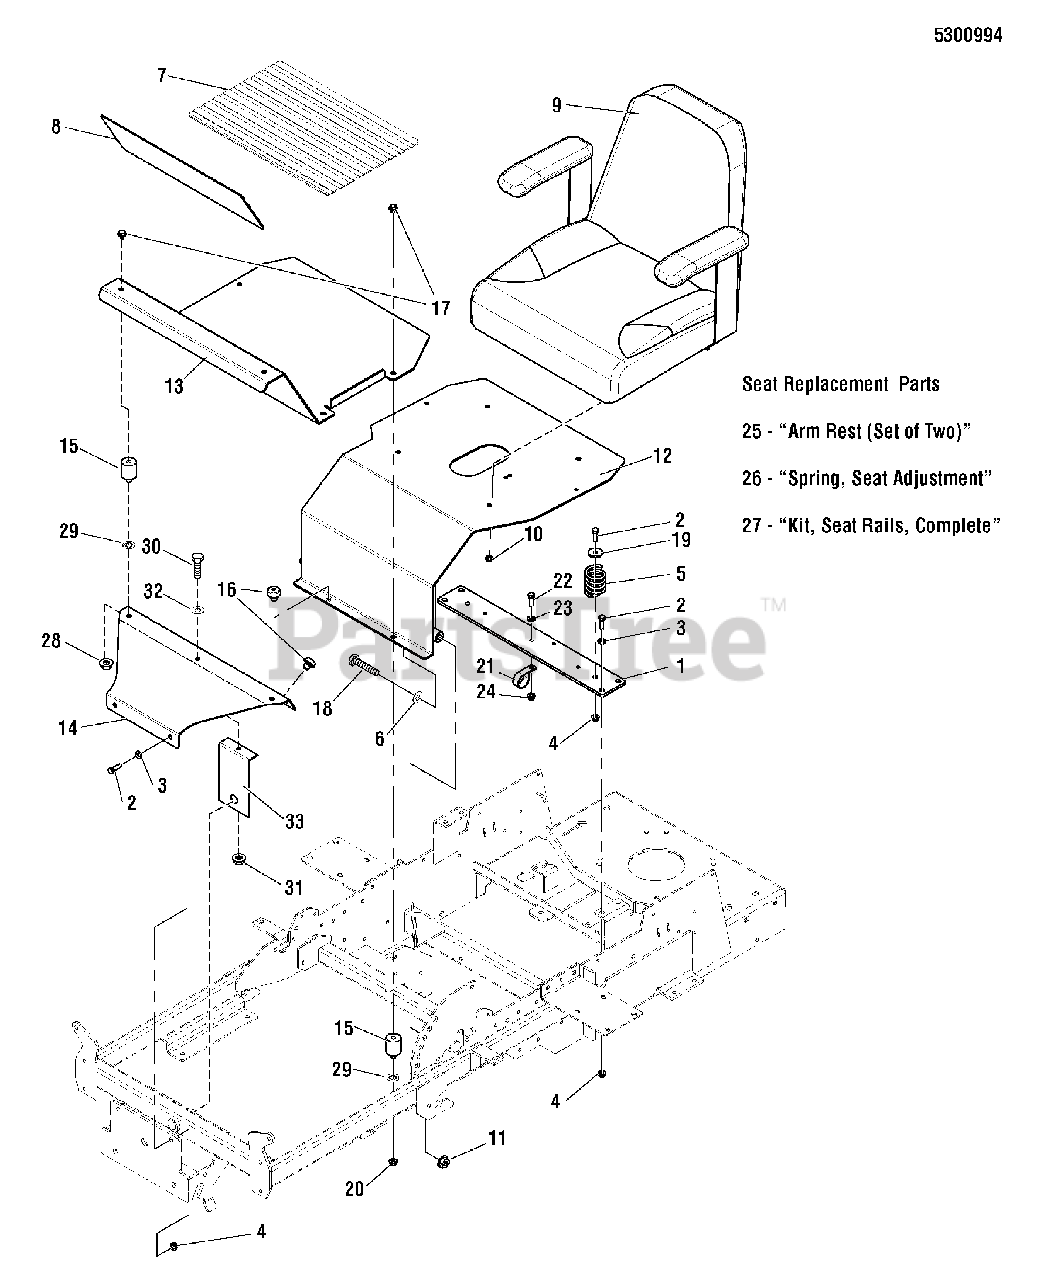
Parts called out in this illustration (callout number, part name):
1	PLATE, SEAT SUPPORT, CONS Z - RED
2	BOLT, 5/16-18 X 1 GD 5 YZ
3	WASHER, 5/16 GD. 9 FLAT
4	NUT, 5/16-18 HEX NYLOCK FLANGE
5	SPRING, SEAT SUPPORT
6	WASHER, 3/8 SAE
7	SAFETY WALK, FLOOR PLATE, 17.38 X 11.50
8	SAFETY WALK, FLOOR REST, 17.38 X 6.00
9	SEAT, XB-180, NO LOGO, BLACK
10	NUT, 5/16-18 HEX NYLON LOCK
11	NUT, 3/8-16 HEX NYLOCK FLANGE
12	WELD, SEAT PLATE - RED
13	PLATE, FLOOR, CONSUMER Z - RED
14	PLATE, FLOOR, FRONT, CONS Z - RED
15	MOUNT, VIBRATION, 30 DURO
16	MOUNT, VIBRATION, RUBBER
17	BOLT, 3/8-16 X 5/8, SERRATED UNDER HEAD
18	BOLT, 3/8-16 X 3-1/2 GD5 YZ
19	WASHER, .34 X 1.25 X 10 GA
20	NUT, 3/8-18 HEX SERRATED FLANGE
21	CLAMP, VINYL INSULATED
22	BOLT, 1/4-20 X 3/4 GD5 YZ
23	WASHER, 1/4 SAE (5025154)
24	NUT, 1/4-20 HEX NYLOCK FLANGE (5025391)
25	ARM REST, SET OF TWO (SV)
26	SPRING, EXTENSION, SEAT ADJUSTMENT (BLK OR SLVR)
27	KIT, SEAT RAILS. COMPLETE (SV)
28	NUT, 3/8-16 HEX NYLOCK FLANGE
29	WASHER, 3/8" ID, INTERNAL TOOTH
30	BOLT, 5/16-18 X 3/4 GD5
31	NUT, 5/16-18 HEX NYLOCK FLANGE
32	WASHER, 5/16" SAE
33	PLATE, SUPPORT, FRONT FLOOR - RED
